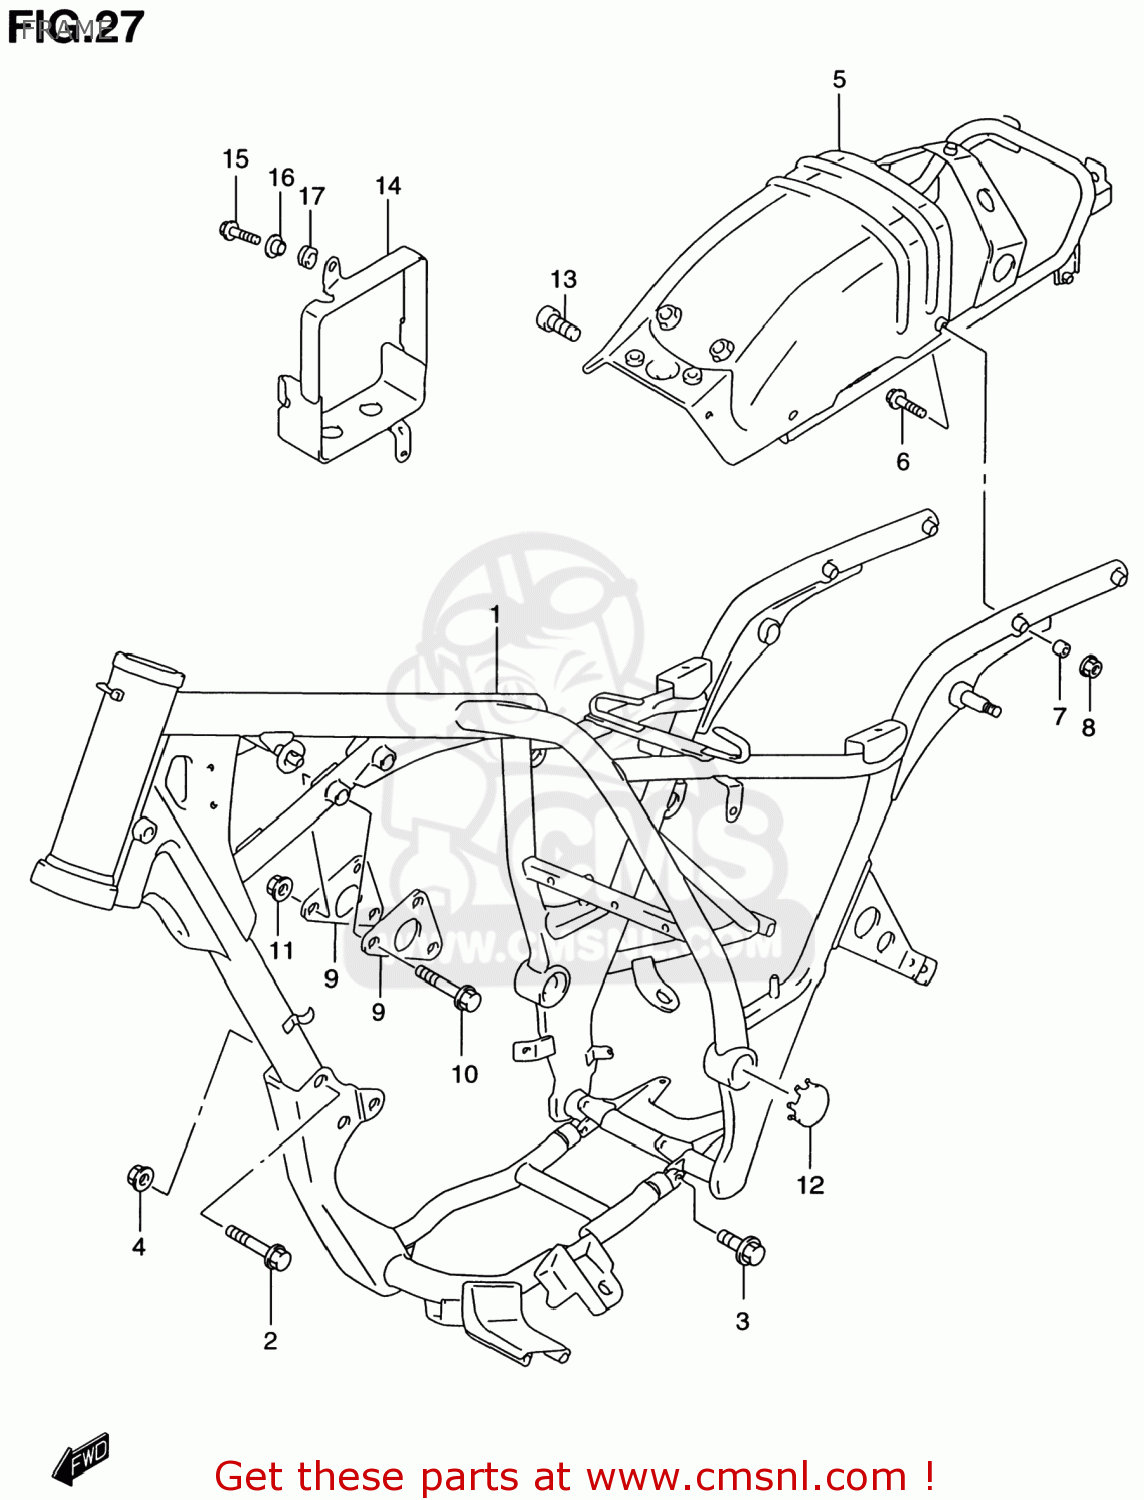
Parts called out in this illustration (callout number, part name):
1	FRAME(BLACK)
2	BOLT
3	BOLT
4	NUT
5	BRACE,RR FRAME
6	BOLT
7	SPACER(8.5X16X10)
8	NUT
9	PLATE,ENG MTG UPR
10	BOLT(8X50)
11	NUT
12	CAP,RR SWINGING ARM PIVOT,R
13	BOLT(6X12)
14	HOLDER,BATTERY
15	BOLT
16	WASHER
17	CUSHION
